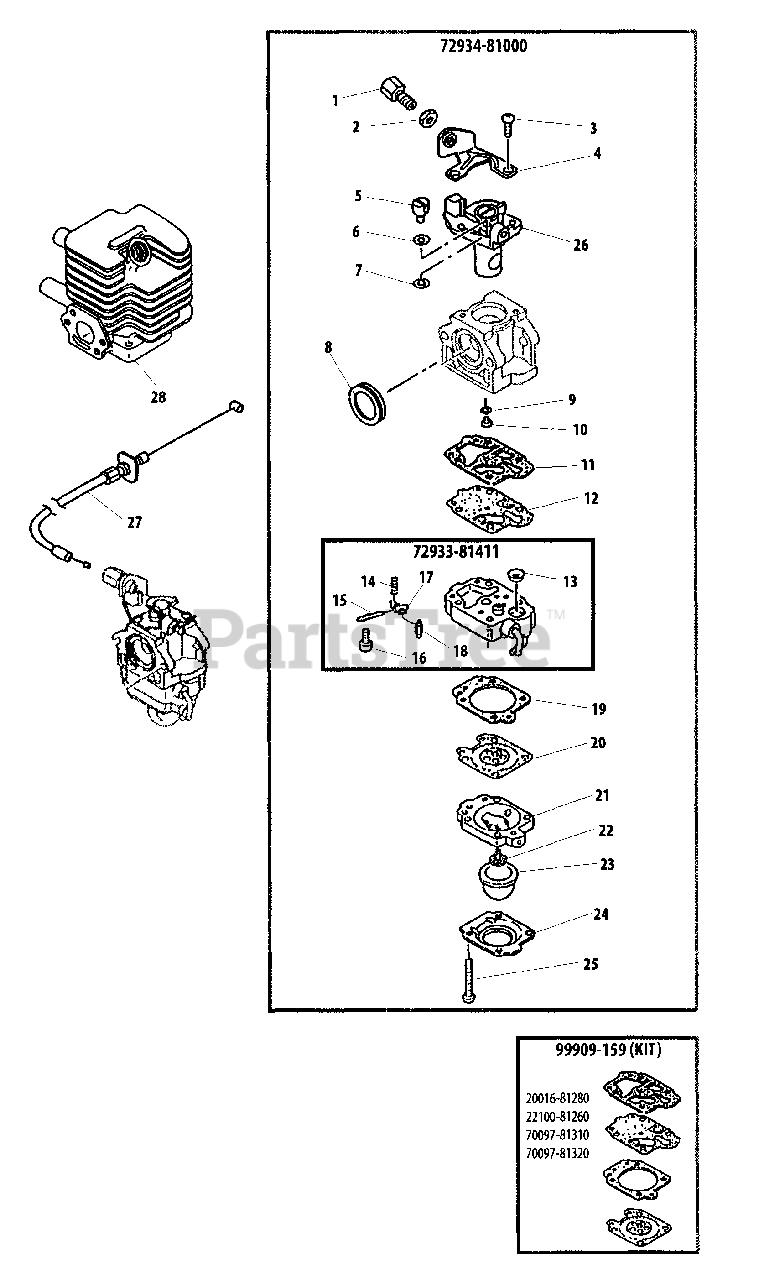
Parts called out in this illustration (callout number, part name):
1	NUT, CABLE ADJUST
2	NUT
3	SCREW
4	BRACKET, CABLE
5	SWIVEL
6	WASHER
7	RING, RETAINING
8	SEAL
9	O-RING
9	BASE, PURGE
10	JET
11	GASKET, PUMP
12	DIAPHRAGM, PUMP
13	STRAINER
14	SPRING, METERING LEVER
15	PIN, METERING LEVER
16	PIN, METERING LEVER
17	LEVER, METERING
18	VALVE, INLET NEEDLE
19	GASKET, METERING
20	DIAPHRAGM, METERING
21	BASE, PURGE
22	VALVE, CHECK
23	BULB, PURGE
24	RETAINER, PURGE BULB
25	SCREW, PUMP COVER
26	THROTTLE VALVE ASSY
27	CABLE, THROTTLE
28	CYLINDER
